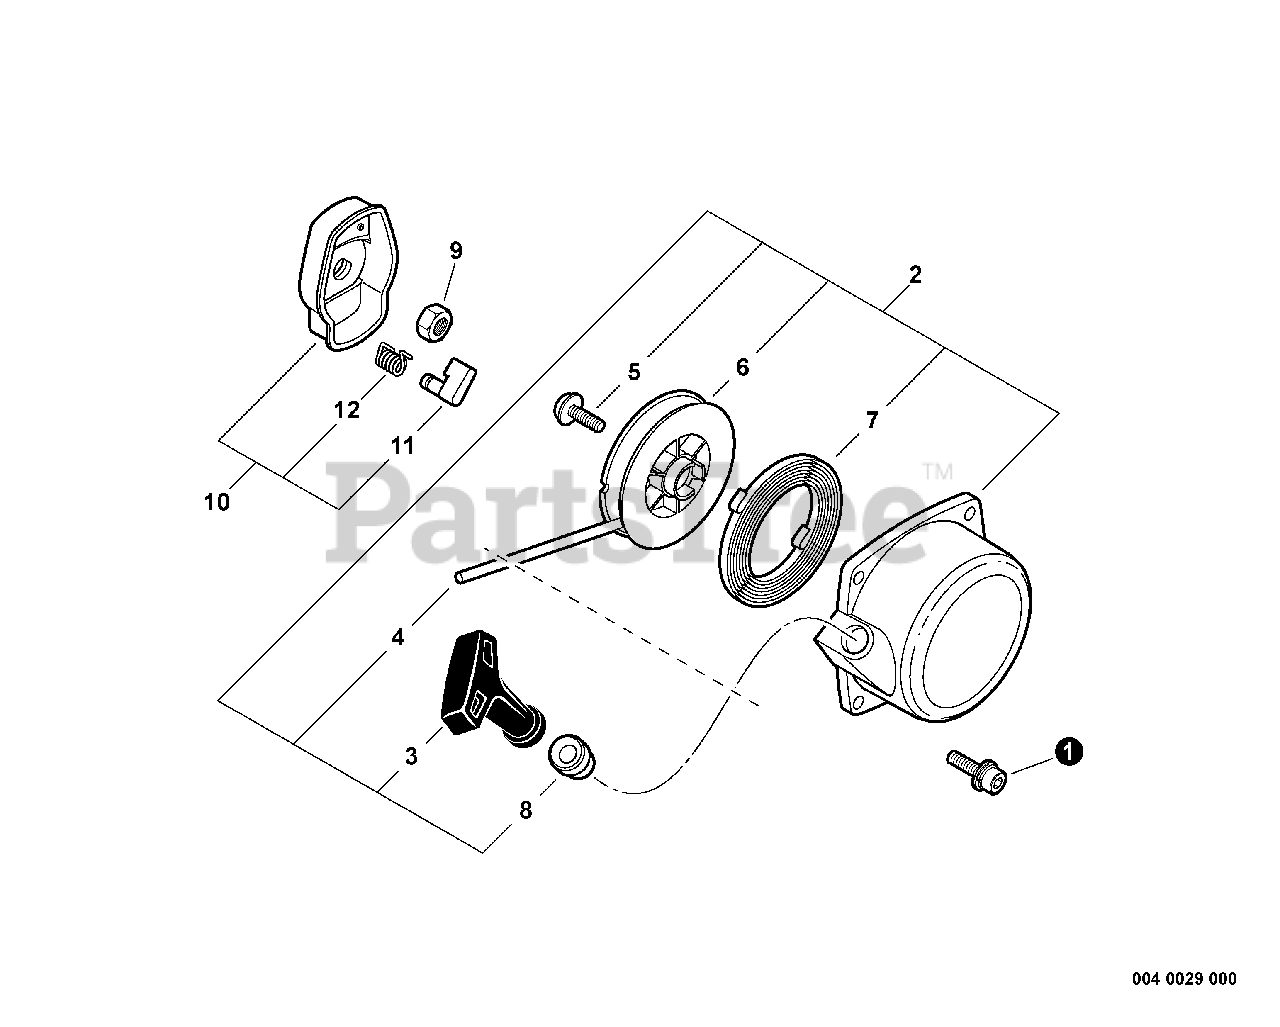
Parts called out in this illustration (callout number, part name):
1	BOLT 4×16
2	STARTER ASSY, RECOIL
3	GRIP, STARTER
4	ROPE, STARTER 3.0×1000
5	SCREW
6	REEL, ROPE
7	SPRING, RECOIL
8	GUIDE, ROPE
10	PAWL ASSY, STARTER
11	PAWL, STARTER - BLACK
12	SPRING, RETURN
